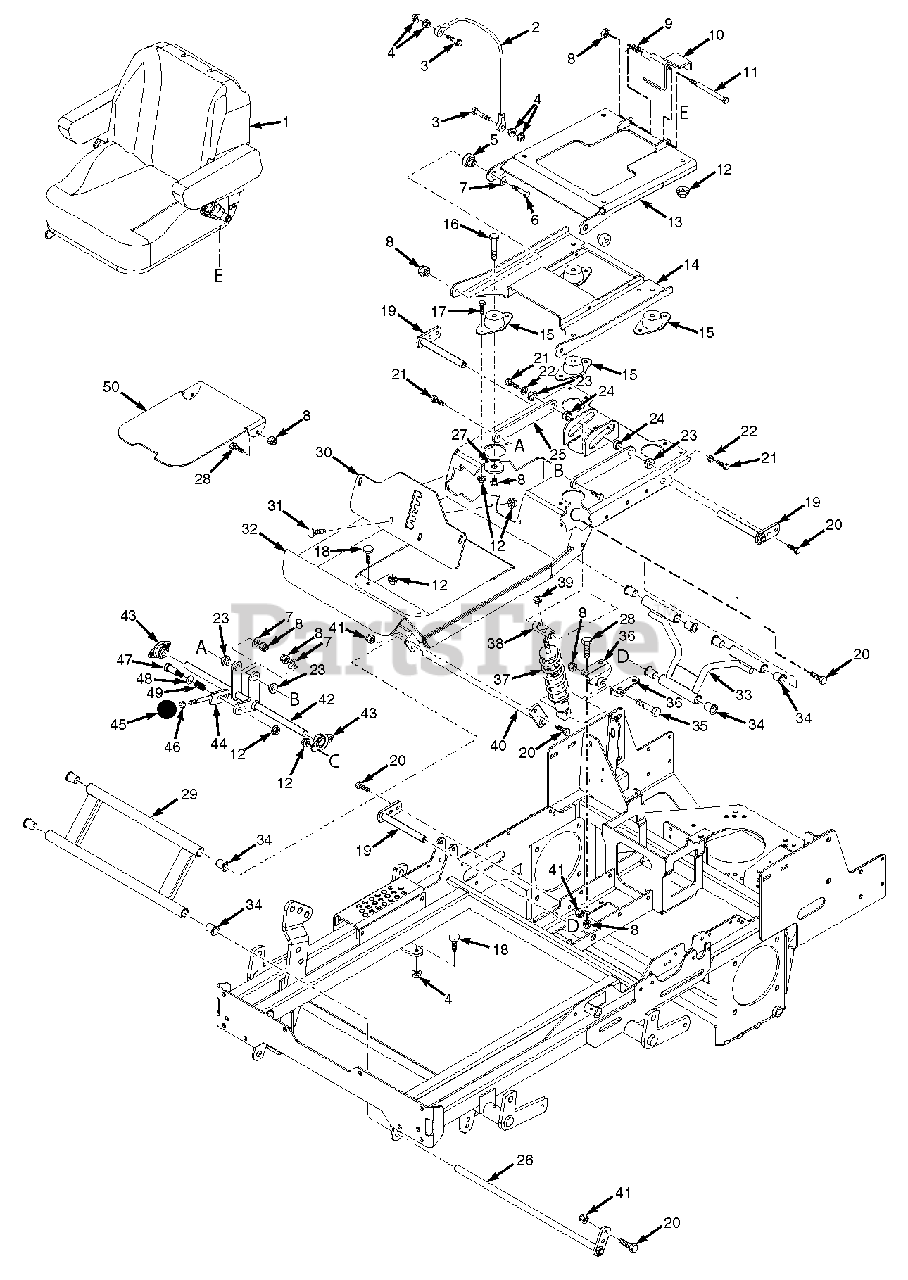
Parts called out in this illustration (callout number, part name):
1	Seat Assembly
2	Cable, Seat Stop
3	Bolt, Hex Head 1/4-20 x 1-1/4"
4	Nut, Serrated Flange 1/4-20
5	Sleeve, Seat Base Mount
6	Bolt, Hex Head 3/8-16 x 2"
7	Flatwasher, 3/8-.391 x .938 x .105
8	Nut, Elastic Stop 3/8-16
9	Spring, Seat Latch
10	Latch Weldment, Seat
11	Bolt, Hex Head 3/8-16 x 6"
12	Nut, Serrated Flange 5/16-18
13	Seat Plate Weldment
14	Seat Mounting Plate Weldment w/Decal
15	Isolator, Seat
16	Bolt, Hex Head 3/8-16 x 2-1/4"
17	Bolt, Hex Head 5/16-18 x 3/4"
18	Bumper, Rubber
19	Shaft Weldment, Rear Op. Platform Pivot
20	Bolt, Hex Head 5/16-18 x 1"
21	Bolt, Hex Head 3/8-16 x 1-1/2"
22	Lockwasher, 3/8" Spring
23	Bushing
24	Bearing
25	Link, Suspension Seat Tensioner
26	Pin Weldment, Op Platform Lower Pivot
27	Flatwasher, 3/8-.406 x 2.25 x .188
28	Bolt, Hex Head 3/8-16 x 1"
29	Suspension Pivot Assembly, Front
30	Bracket, Suspension Adjustment w/Decal
31	Bolt, Carriage 5/16-18 x 1"
32	Seat Mounting Base Weldment w/Decal
33	Suspension Pivot Assembly, Rear
34	Bearing
35	Bolt, Hex Head 3/8-16 x 2-3/4"
36	Mount Weldment, Shock
37	Shock Absorber, Suspension
38	Mount, Suspension Shock
39	Nut, Elastic Stop 3/8-24
40	Pin Weldment, Op Platform Upper Pivot
41	Nut, Elastic Stop 5/16-18
42	Pivot Weldment, Suspension Tensioner
43	Bearing, Self Align 5/8" ID
44	Adjustment Lever, Suspension
46	Nut, Jam 3/8-16
47	Bolt, Shoulder 3/8 x 1"
47	Bolt, Shoulder 3/8 x 3/8"
48	Flatwasher, 3/8-.406 x .812 x .065
49	Spring
50	Cover, Foot PLate
